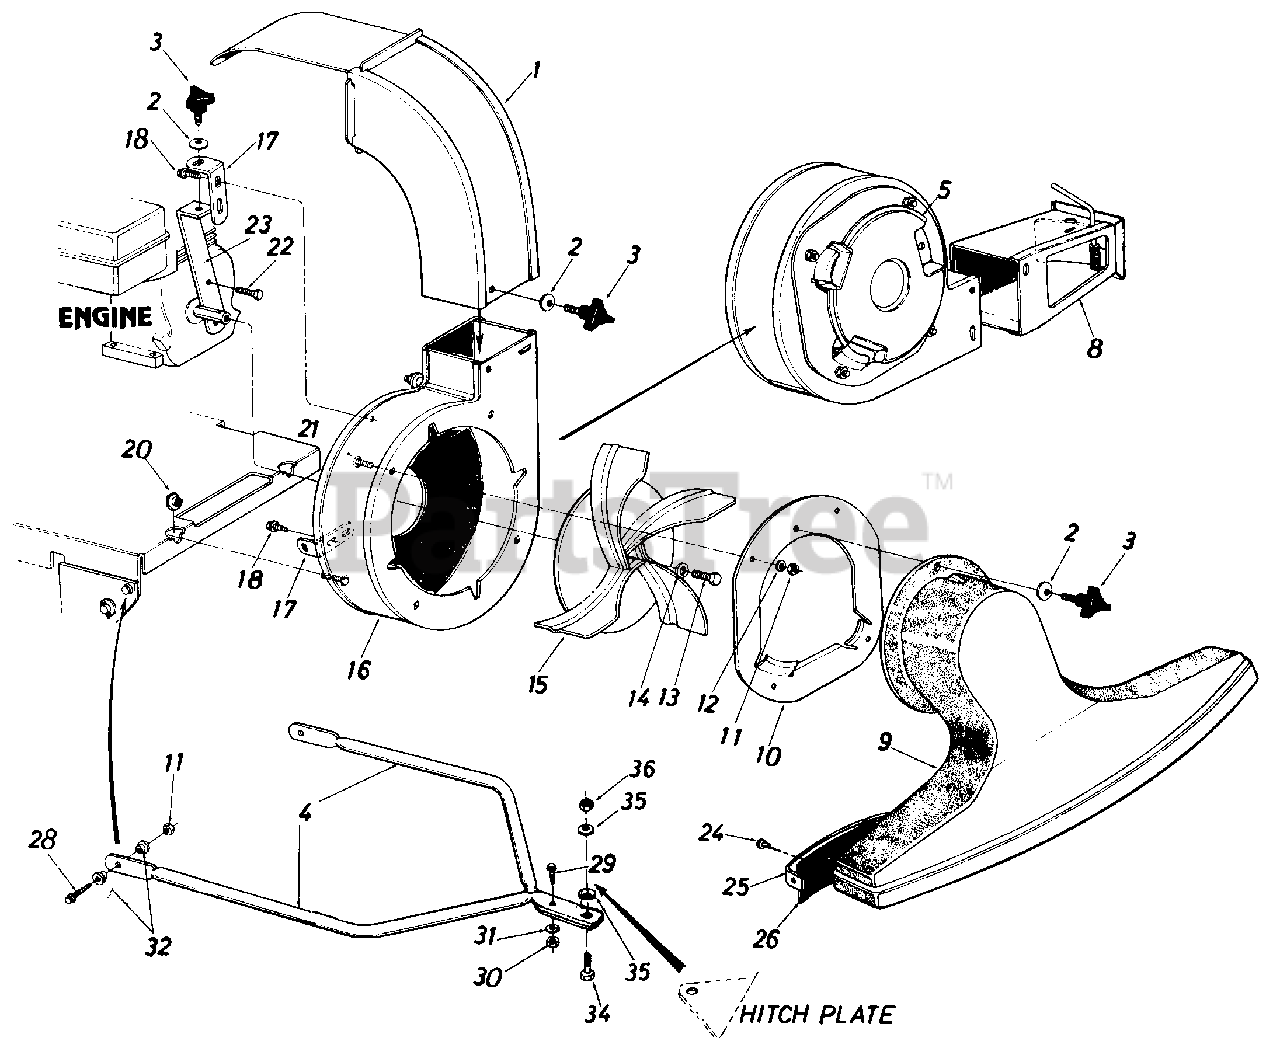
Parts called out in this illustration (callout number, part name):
3	3-Arm Thumb Scr. 5/16-18 x .75" Lg.
10	Nozzle Plate Ass'y.
11	Hex Nut 5/16-18 Thd.
12	L.-Wash. 5/16" I.D.
13	Hex Bolt 3/8-24 x 1.25" Lg.*
14	L.-Wash. 3/8" I.D. H.D.
15	Air Vane Plate Ass'y. w/pulley
20	Hex Shoulder Nut .50 I.D.
21	Carriage Bolt 5/16-28 x .62" Lq.*
22	Hex Locking Bolt 5/16-24 x .75" Lg.
28	Hex Bolt 5/16-18 x 1.00" Lg.*
29	Truss Mach. Scr. 1/4-20 x .75" Lg.*
30	Hex Nut 1/4-20 Thd.*
31	L.-Wash. 1/4" I.D.
32	Shoulder Spacer
34	Shld. Bolt .496 Dia.
35	Belleville Wash. .39 I.D. x 1.12 O.D.
36	Hex Jam L-Nut 3/8-26 Thd.
